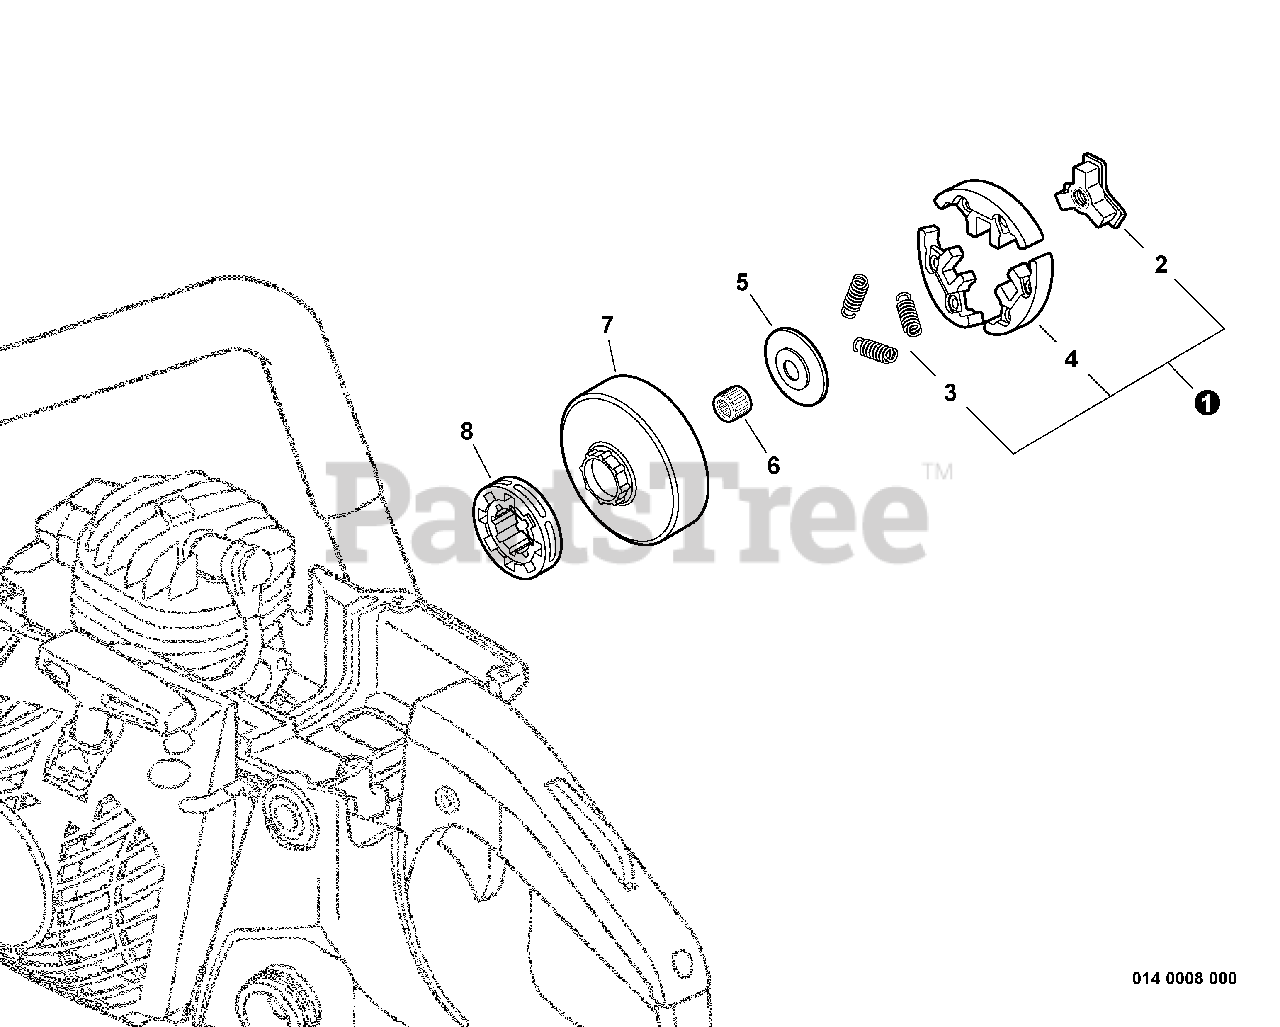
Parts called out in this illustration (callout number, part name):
1	CLUTCH ASSY
2	HUB, CLUTCH
3	SPRING, TENSION
4	SHOE SET, CLUTCH (3PCS)
5	PLATE, CLUTCH
6	BEARING, NEEDLE
7	DRUM, CLUTCH
8	SPROCKET, 0.325 RIM
